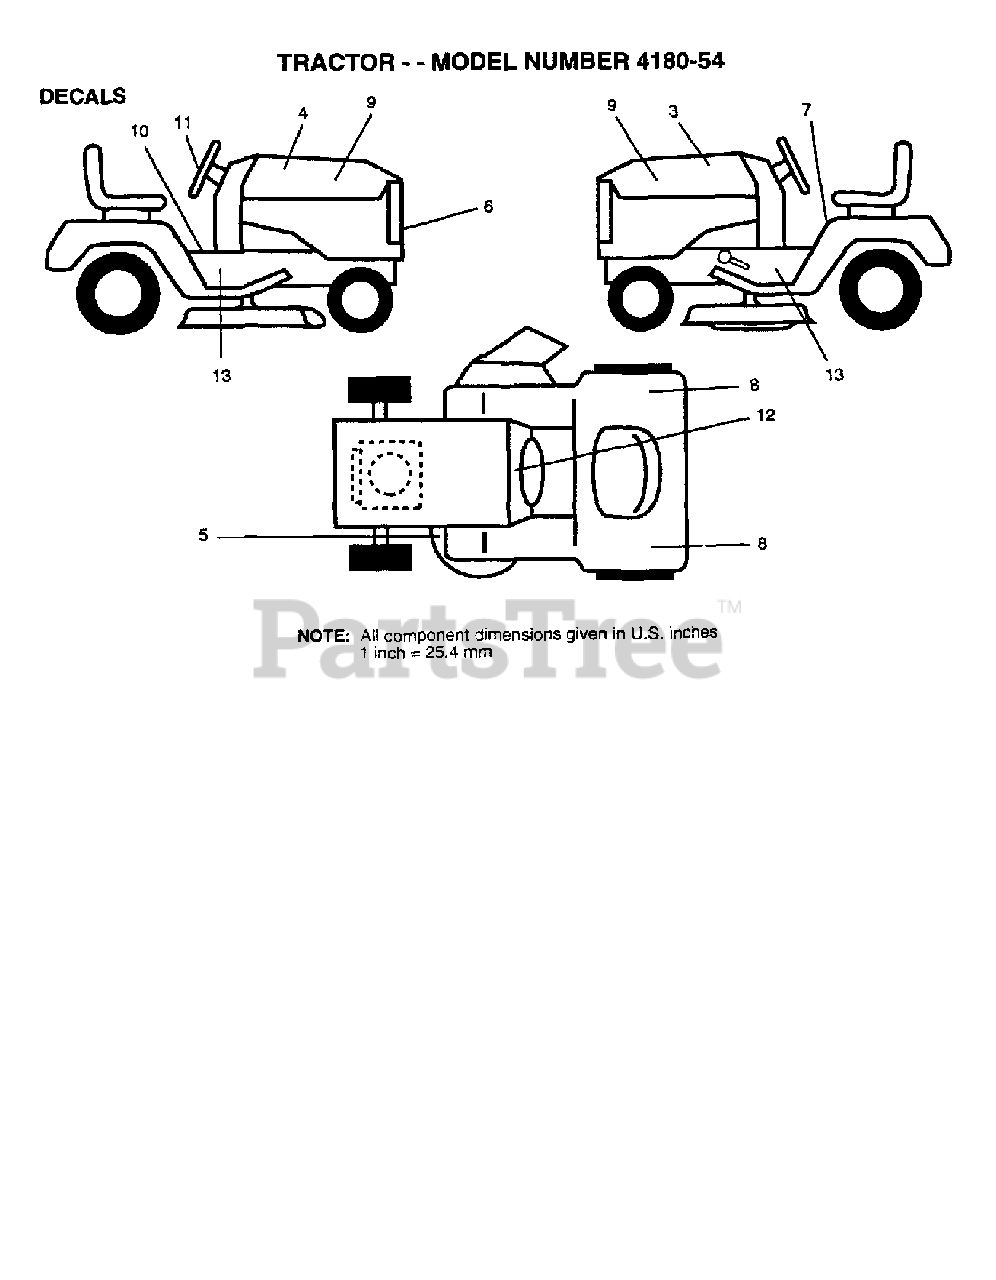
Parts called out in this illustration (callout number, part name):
2	DECAL ENGINE HP
3	Poulan TBD
4	Poulan TBD
6	Poulan TBD
7	DECAL LT
8	REFLECTOR-TAIL YT
9	Poulan TBD
10	DECAL PARK BRAKE
11	Poulan TBD
13	Poulan TBD
